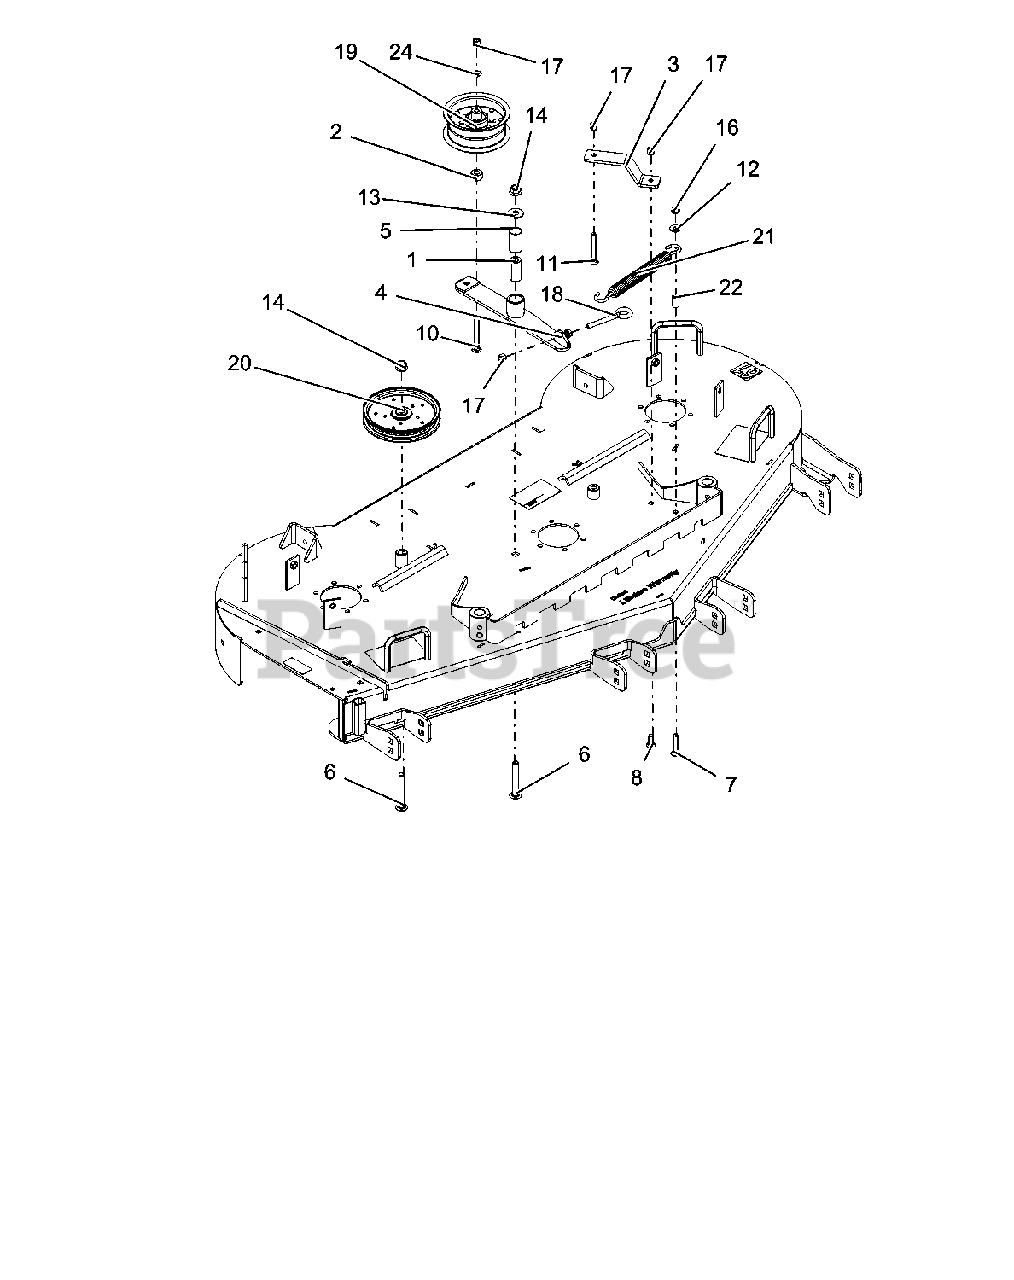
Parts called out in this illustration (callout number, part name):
1	BSHG, SPCR .502X.997X2.03
2	SPACER, .437X1.00X.58 SMLS
3	STRAP, IDLER 48/52 WALK-BLACK
4	WLDMT, IDLER 61 WALK-BLACK
5	BSHG, 1.00X1.125X1.937
6	BLT-RHDSSQNK .50-13X3.50 G5YZ
7	BLT-RHDSSQNK .38-16X2.00 G5YZ
8	BLT-RDHDSHSQNK.38-16X1.0 G5YZ
10	BLT-RDHDSQNK .38-16X3.50 G5 YWZC
11	BLT-RDHDSQNK .38-16X3.00 G5 YWZC
12	WSHR-FL-STL.438X1.00X.083 YWZC
13	WSHR-FL-STL.563X1.38X.109YWZC
14	NUT-LK-NYL-FLG .50-13 YWZC
16	@NUT-SPNLK-FLG .375-16 YWZC
17	NUT-LK-NYL .38-16 YWZC
18	BOLT, EYE .38-16X4.50 .75 DIA
19	PULLEY, FLAT 5.00X2.36X.375
20	IDLER-FLAT-PLY 6.75X.510
21	SPRG, EXTENSION - SWIVEL
22	BUSH.,S.391X.622X.95 ST REV A
24	WSHR-FL-STL.406X.812X.065 YWZ
